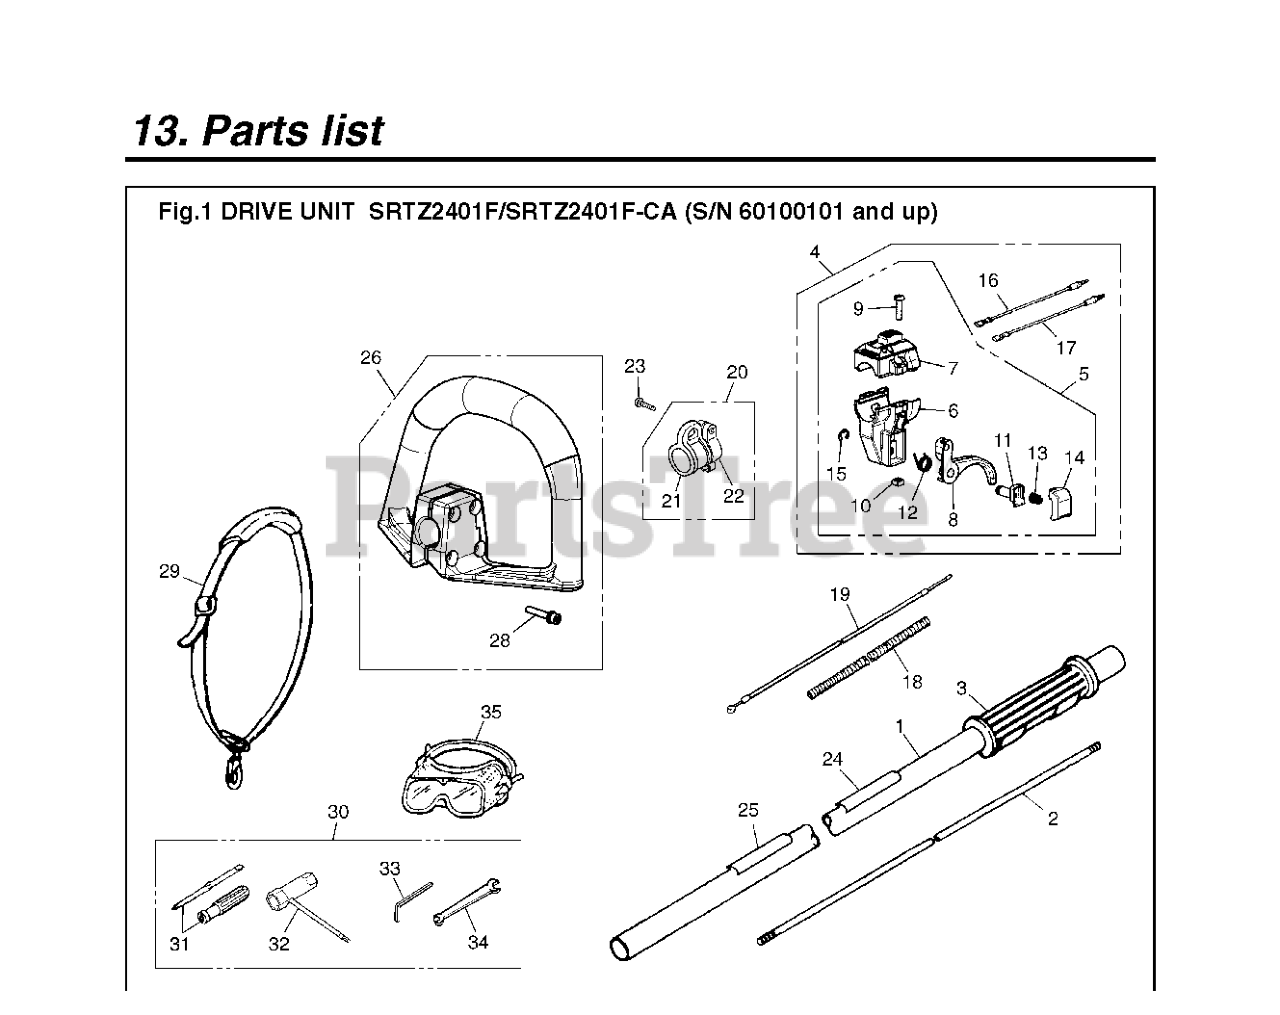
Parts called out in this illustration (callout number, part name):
1	PIPE-C
4	LEVER COMP (RPLS 8488R20343)
5	LEVER (FLEX. LEVER)(RPLS -13)
7	COVER COMP (RPLS 611014410-02)
16	CORD (A), BLACK
17	CORD (B), RED
20	HANGER COMP.
21	HANGER
26	HANDLE ASSY. (RPLS T319514001)
29	HARNESS-ASSY***
30	TOOL-SET
35	GOGGLExxx (RPLS
